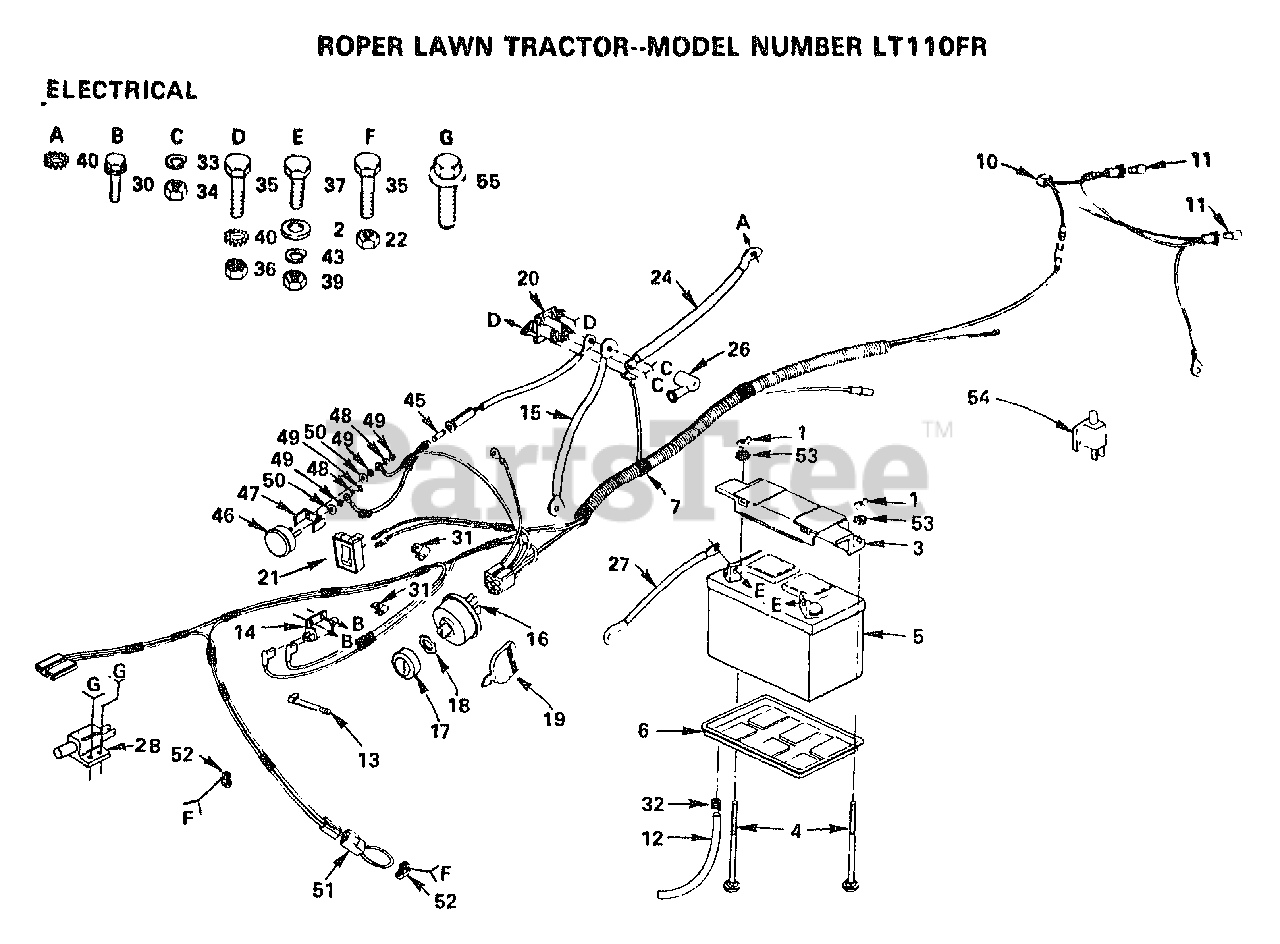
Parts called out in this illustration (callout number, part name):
2	WASHER
4	BOLT
6	"TRAY, BATTERY LT"
10	HARNESS T
13	WIRE TIE
15	"CABLE T, BATTERY"
27	CABLE ASSY LT
28	SWITCH T
29	"NUT,KEPS"
31	CLIP T
32	HOSE CLAMP T
34	NUT
35	BOLT
36	NUT
43	LOCKWASHER
45	FUSE-30 AMP
46	AMMETER T
52	CLIPT
53	LOCKWASHER GT
54	SWITCH-INTER. GT
55	SCREW
